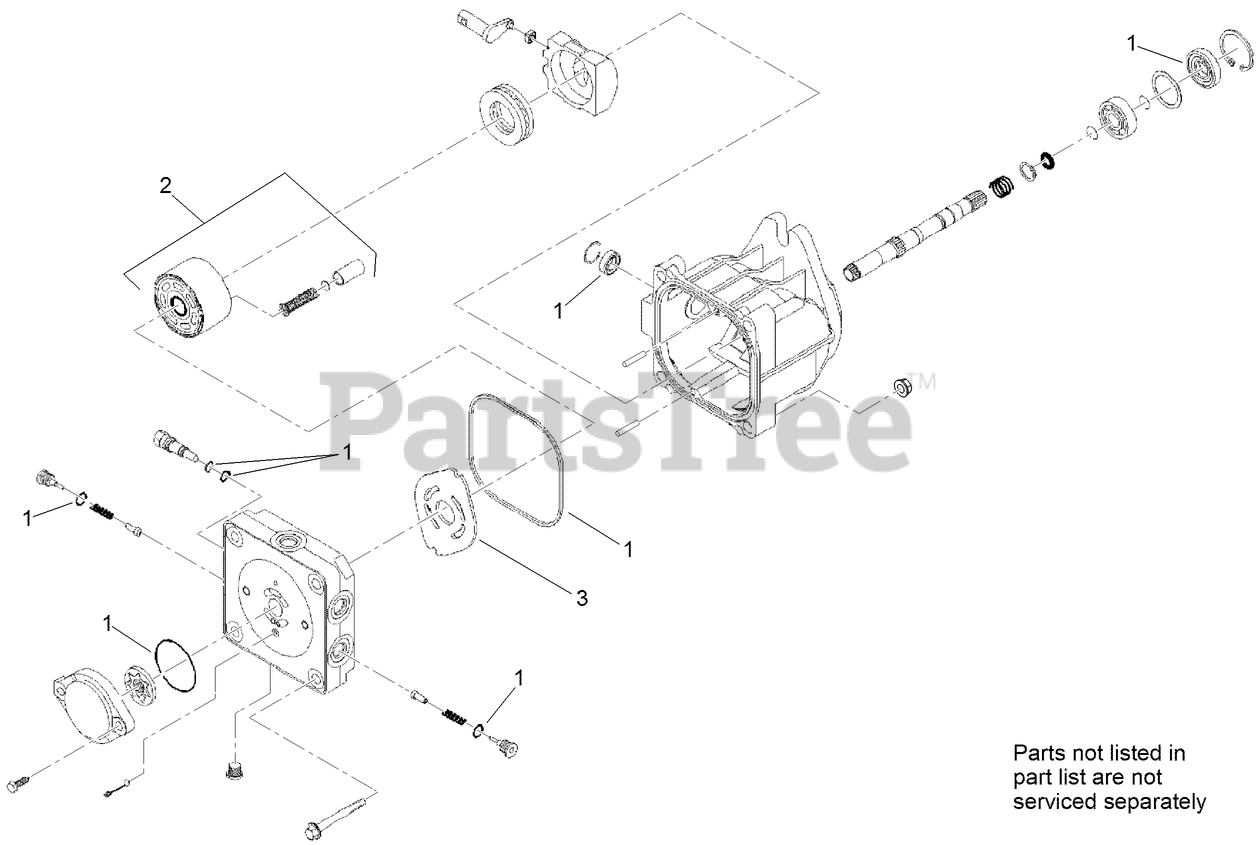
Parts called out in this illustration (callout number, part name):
1	OVERHAUL SEAL KIT
2	CYLINDER BLOCK ASM
3	PLATE-VALVE
